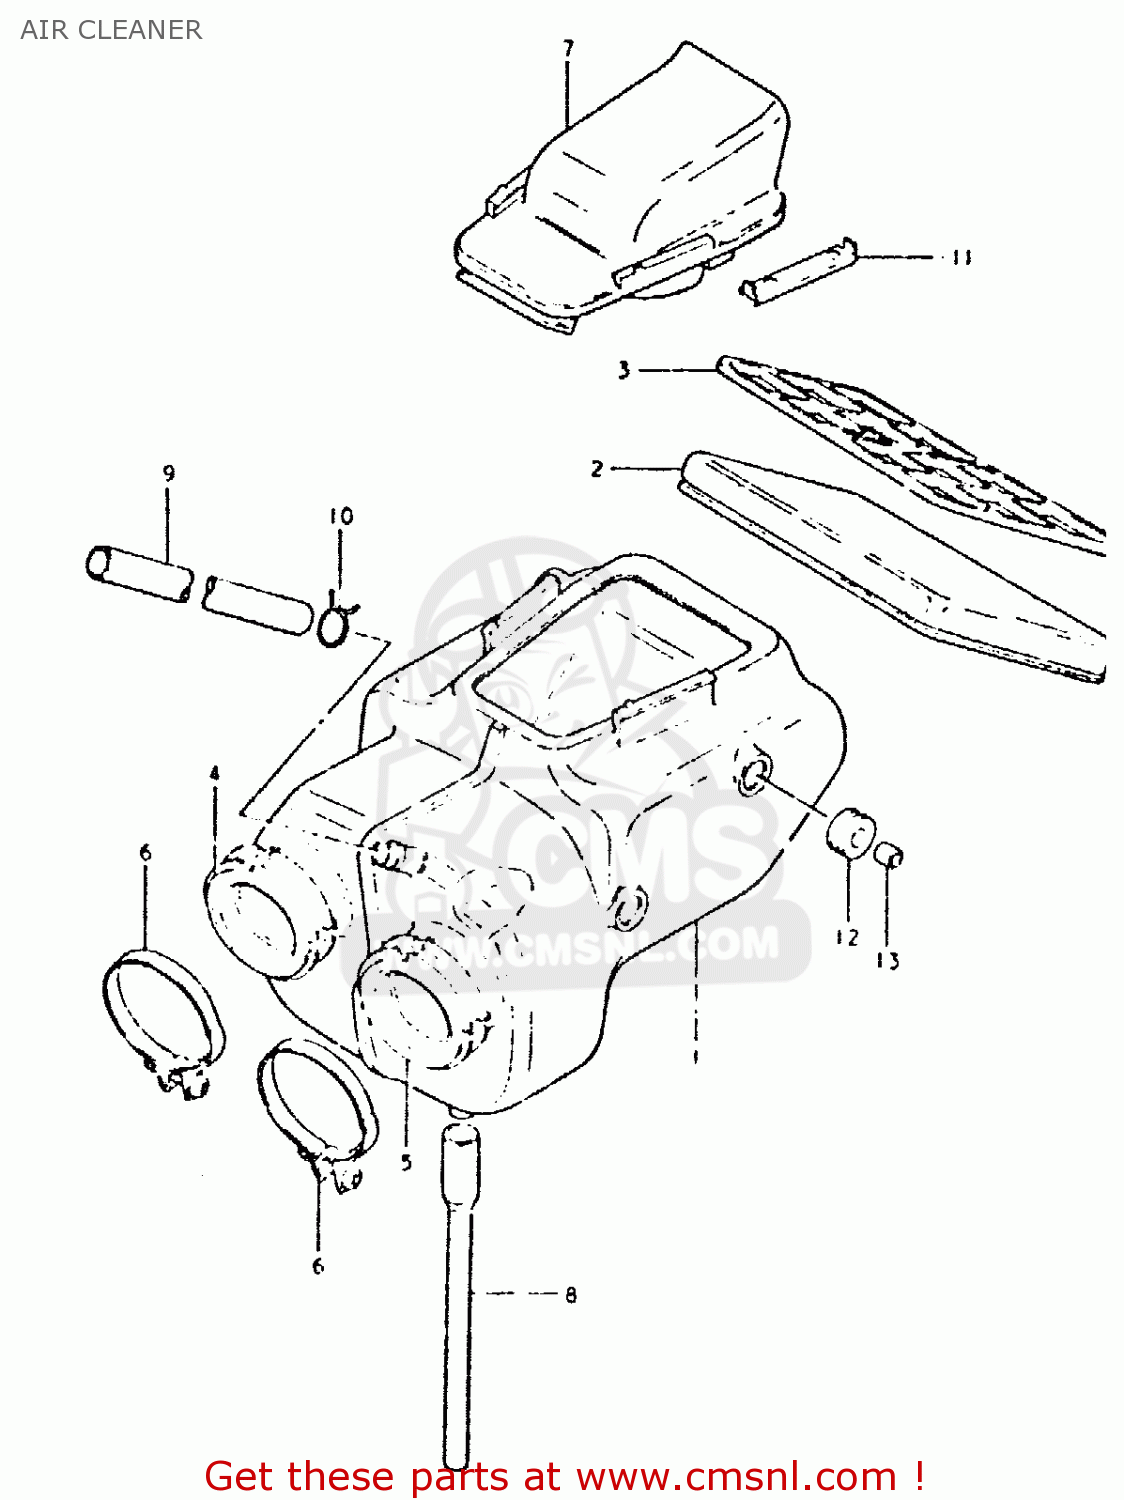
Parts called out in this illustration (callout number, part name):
1	CLEANER ASSEMBLY,AIR
2	FILTER
3	HOLDER NO.2
4	OUTLET,R
5	OUTLET,L
6	CLAMP
7	CAP
8	DRAIN TUBE
9	TUBE,BREATHER
10	CLAMP
11	SLIDER
12	CUSHION
13	SPACER(6.1X9X7.5)
